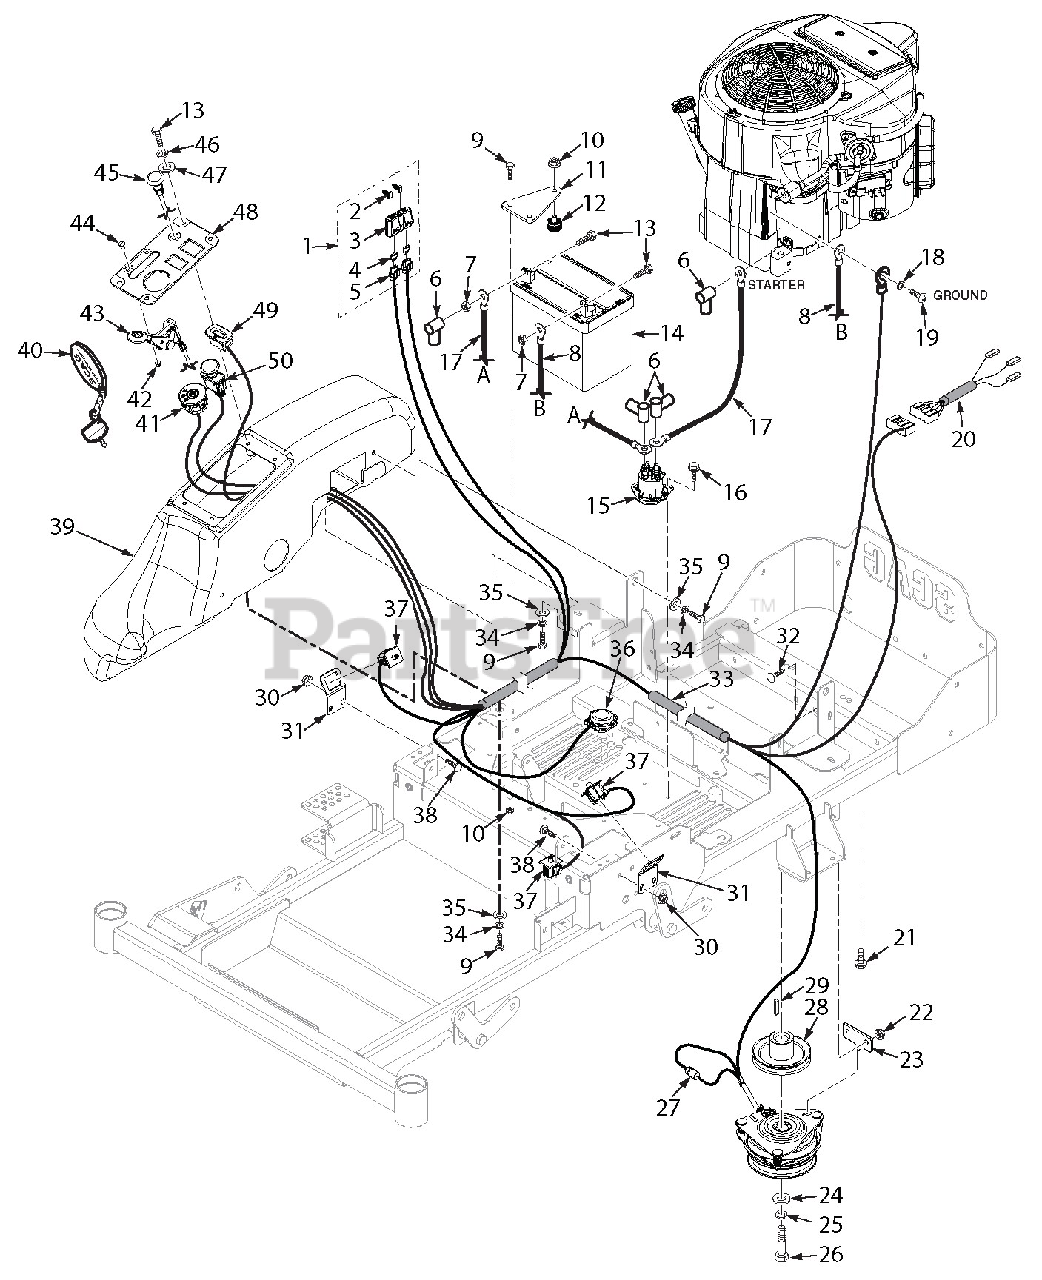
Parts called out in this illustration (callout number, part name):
1	Double Fuse Assembly
2	Clip, Wire
3	Cover, Double
4	Fuse, 20 Amp
5	Fuse Holder
6	Rubber Boot
7	Nut, 1/4-20 UNC
8	Battery Cable, Black 31.50
9	Bolt, Hex Head 5/16-18 x 3/4"
10	Nut, 5/16-18 Serrated Flange
11	Battery Hold Down
12	Bumper, Rubber
13	Bolt, Hex Head 1/4-20 x 1/2"
14	Battery, 12v - 230CCA
15	Solenoid, Sealed
16	Screw, Self-Tapping 1/4-20 x 3/4
17	Battery Cable, Red 18.0 w/Braid
18	Lockwasher, 5/16" Ext.
19	Bolt, Hex Head M8 x 1-1/4 x 16
20	Wire Harness Adapter, Kawasaki
21	Bolt, 3/8-16 x 1-1/4" Serrated Flange Self Tap
22	Nut, 5/16-18 Flange Elastic Stop
23	Plate, Anti-Rotation
24	Flatwasher, 7/16-.496 x 1.75 x .25
25	Lockwasher, 7/16"
26	Bolt, 7/16-20 x 3" w/Patch
27	Diode, 600V 6 Amp
28	Pulley, 4-1/2" - 1" Bore
29	Key, 1/4 x 1/4 x 1-1/4"
30	Nut, 1/4-20 Flange Elastic Stop
31	Bracket, Switch
32	Bolt, Carriage 5/16-18 x 3/4"
33	Wire Harness
34	Lockwasher, 5/16"
35	Flatwasher, 5/16-.375 x .875 x .083
36	Switch, Double Pole - Twist
37	Switch, Double Pole - Plunger
38	Bolt, Carriage 1/4-20 x 3/4"
39	Console Tank, SZL-36
40	Key Fob Assembly
41	Ignition Switch
42	Nut, #10-24 Elastic Stop
43	Throttle Control, Kawasaki
44	Bolt, Carriage #10-24 x 1/2"
45	Choke Control, Kawasaki
46	Lockwasher, 1/4"
47	Flatwasher, 1/4-.312 x .750 x .065
48	Instrument Panel w/Decal, SZL-36
49	Hourmeter
50	Switch, PTO
